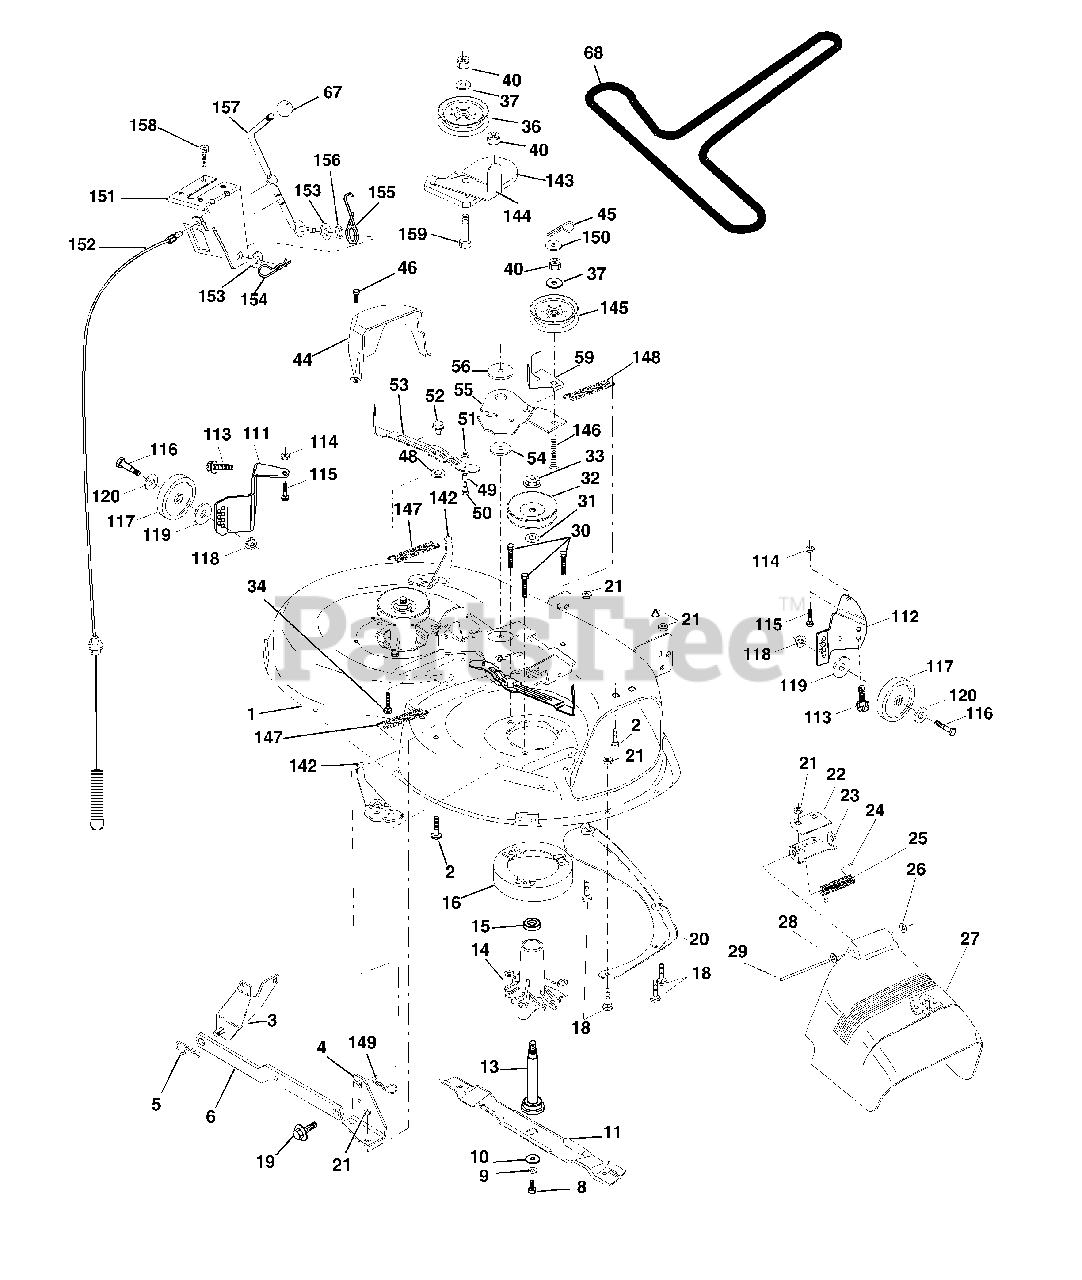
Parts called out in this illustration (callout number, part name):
1	Mower Deck Assembly, 42"
2	Bolt
3	Bracket Asm Fr. Sway Bar 3/42
4	Bracket Asm Deck 42" Sway Bar
5	Retainer Spring
6	Arm, Suspension, Rear
8	Bolt 3/8-24 x 25 Grade 8 patched
9	Washer, Lock
10	Washer, Hardened
11	Blade
13	Shaft Assembly, Mandrel, Vented
14	Housing, Mandrel, Vented
15	Bearing, Ball, Mandrel
16	Stripper, Mower Deck
18	Bolt, Carriage 5/16-18 x 5/8
19	Bolt, Shoulder
20	Baffle, Vortex
21	Nut
22	Stiffener Bracket
23	Bracket, Deflector Mower 42"
24	Cap, Sleeve 80 x 112 Blk Mower
25	Spring, Torsion, Deflector 2 52
26	Nut, Push Phos & Oil
27	Shield, Deflector 42" Blk
28	Washer 11/32 x 5/8 x 16 Gauge
29	Rod, Hinge 42" 6 75 W/G
30	Screw Thdrol Washer Head
31	Washer, Spacer Mower Vented
32	Pulley, Mandrel
33	Nut, Toplock
34	Bolt
36	Pulley, Idler, Flat
37	Washer 13/32 x 13/16 x 16 Gauge
40	Nut
44	Guard, Mandrel, LH
45	Retainer
46	Screw, Thdrol 1/4-20 x 5/8 T
48	Washer, Hardened
49	Roller Assembly, Cam Follower
50	Bolt, Shoulder #10-24 Grade 5
51	Locknut
52	Bolt, Shoulder 5/16-18 UNC
53	Arm Assembly, Pad, Brake
54	Washer, Hardened
55	Arm, Idler
56	Spacer, Retainer
59	Guard TUV Idler
67	Knob
68	V-Belt, 42" Mower
111	Bracket, Gauge, Wheel LH
112	Bracket, Gauge, Wheel RH
113	Screw Tapping 5/16 - 18 x 1/2
114	Nut, Keps 5/16 - 18 UNC
115	Bolt, Carriage 5/16-18 x 1/2
116	Bolt, Shoulder
117	Wheel, Gauge
118	Nut Centerlock 3/8-16
119	Washer 3/8 x 7/8 x 14 Ga.
120	Washer 17/32 x 15/16 x 12 Ga.
142	Arm Spring Brake Mower
143	Bracket Arm Idler 42"
144	Keeper Belt 42" Clutch Cable
145	Pulley Idler Flat
146	Bolt Carriage Idler
147	Spring Extension
148	Spring Return Idler
149	Retainer Spring Yellow
150	Washer 9/32 x 3/4 x 16 Ga.
151	Bracket Clutch Cable
152	Clutch Cable 42"
153	Washer Flat 3/8" Type B
154	Spring Retainer
155	Spring Retention LVR CLTCH CAB
156	Spacer Clutch Cable
157	Rod Clutch Cable 3/8"
158	Screw Hex Thd Cut 1/4-20 x 5/8
159	Bolt Rdhd Sqn 3/8-16 UNC x 1-3/4
